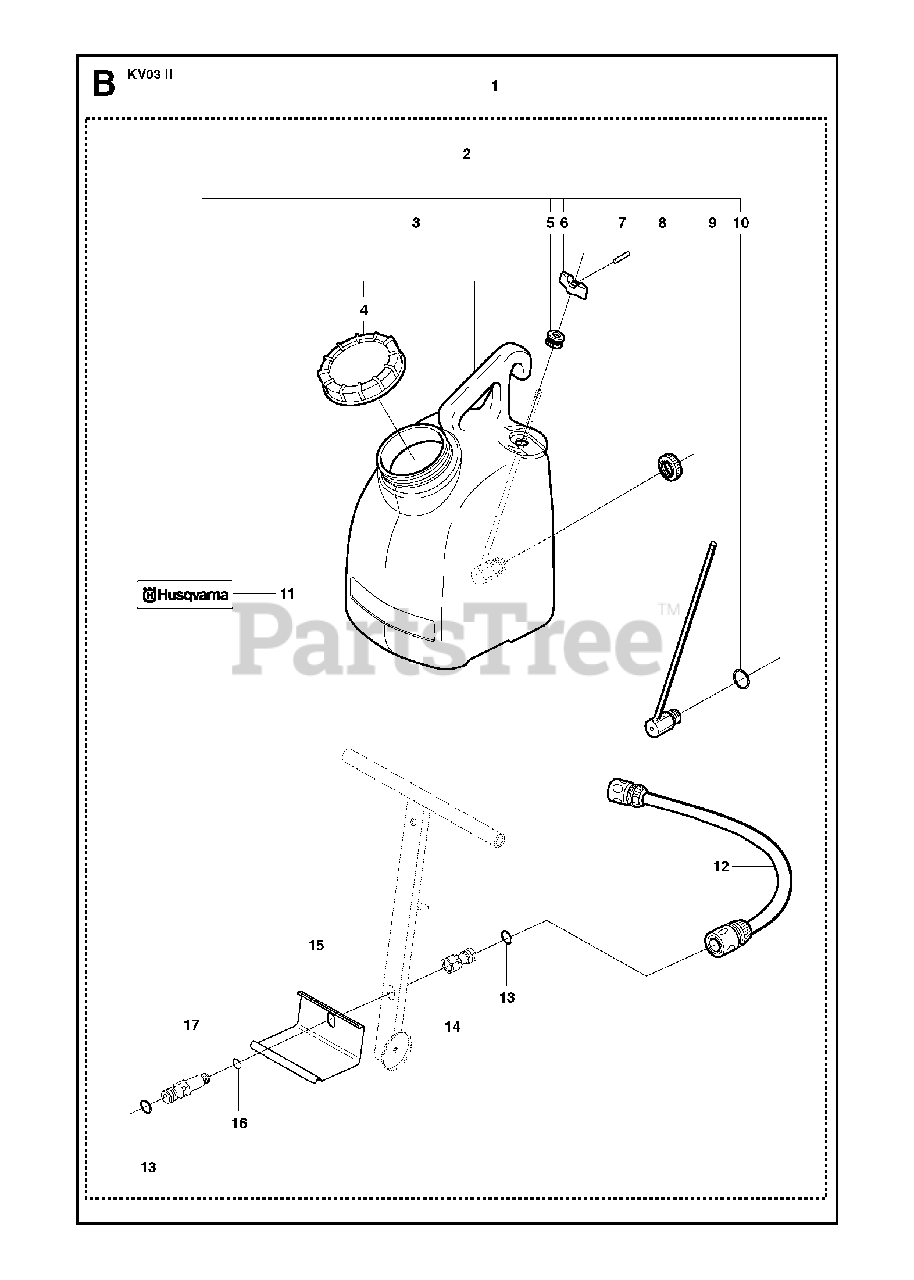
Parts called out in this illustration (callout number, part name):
1	CUTTING TROLLEYIncl. 2 - 17
2	WATER TANKIncl. 3 - 11
5	ANTIVIBRATION ELEMENT
12	HOSE
